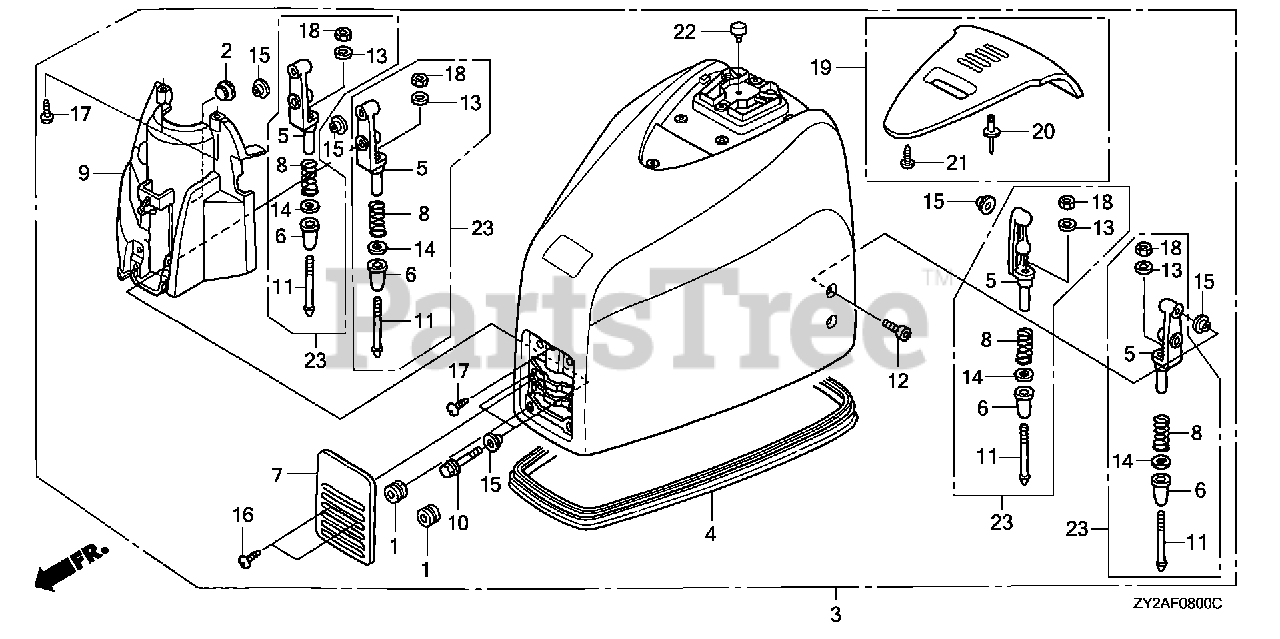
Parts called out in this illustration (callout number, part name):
1	GROMMET, AIR CLEANER HOUSING
2	GROMMET, WIRE
3	COVER ASSY., ENGINE *NH282MU* (OYSTER SILVER METALLIC-U)
4	SEAL, ENGINE COVER
5	BRACKET, HOOK
6	DAMPER, HOOK
7	COVER, FR. *NH282MU* (OYSTER SILVER METALLIC-U)
8	SPRING, LOCK ADJUSTER
9	DUCT, ENGINE COVER
10	BOLT, FLANGE (6X20)
11	BOLT, COVER LOCK
12	BOLT, SOCKET (6X16)
13	WASHER, PLAIN (6MM)
14	WASHER, PLAIN (12MM)
15	COLLAR, DISTANCE (6.5X9X3)
16	SCREW, TAPPING (4X10)
17	SCREW, TAPPING (4X10)
18	NUT, HEX. (6MM)
19	COVER KIT, TOP *NH282MU* (OYSTER SILVER METALLIC-U)
20	RIVET (4.1X27.7)
21	SCREW, TAPPING (4X10)
22	RUBBER B, STAND STOPPER
23	HOOK KIT, COVER
